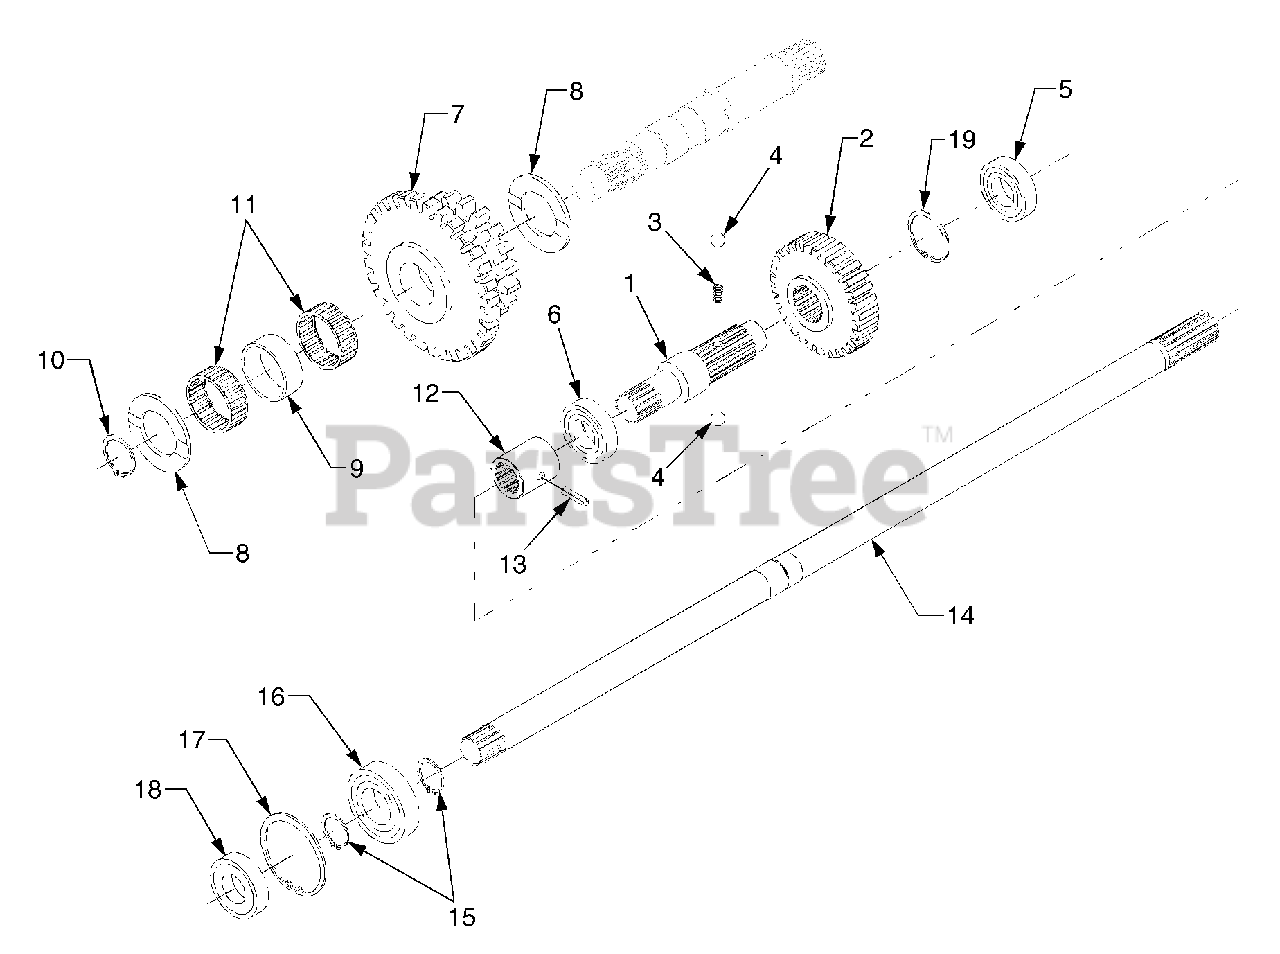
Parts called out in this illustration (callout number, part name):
1	Shaft, Front Wheel Driving
2	Gear, 31 Spur
5	Bearing, Ball
6	Bearing, Ball
8	Collar, Thrust
11	Bearing, Needle
14	Shaft 1, Propeller
16	Bearing, Ball
